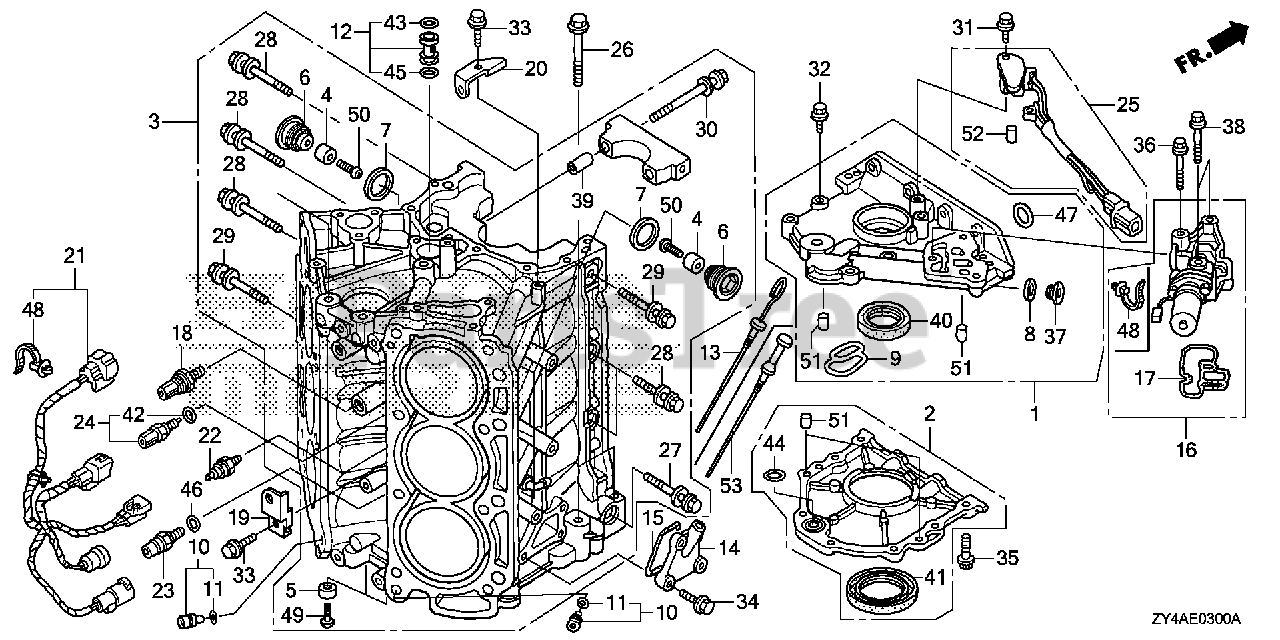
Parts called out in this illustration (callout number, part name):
1	COVER ASSY., CRANKCASE (UPPER) *NH8* (DARK GRAY)
2	CASE ASSY., OIL SEAL
3	BLOCK ASSY., CYLINDER *NH8* (DARK GRAY)
4	METAL, ANODE
5	METAL, ANODE
6	BOLT, SEALING (22MM)
7	WASHER, SEALING (22MM)
8	WASHER, SEALING (22MM)
9	GASKET, OIL HOLE
10	ORIFICE ASSY., OIL CONTROL
11	O-RING (8.8X2.4)
12	JOINT ASSY., OIL PIPE
13	DIPSTICK, OIL
14	COVER, OIL LEVEL GAUGE
15	GASKET, OIL LEVEL GAUGE
16	VALVE ASSY., SPOOL *NH8* (DARK GRAY)
17	FILTER ASSY., SPOOL VALVE
18	SENSOR, KNOCK
19	BRACKET, CLIP B
20	BRACKET B, HARNESS CLIP
21	WIRE, SWITCH
22	SWITCH ASSY., OIL PRESSURE
23	SWITCH ASSY., OIL PRESSURE
24	SENSOR ASSY., WATER TEMPERATURE
25	SENSOR ASSY., CRANK
26	BOLT, FLANGE (12X95)
27	BOLT-WASHER (10X109)
28	BOLT-WASHER (10X60)
29	BOLT-WASHER (10X80)
30	BOLT-WASHER (11X105)
31	BOLT, FLANGE (6X16)
32	BOLT, FLANGE (6X35)
33	BOLT, FLANGE (6X14)
34	BOLT, FLANGE (6X18)
35	BOLT, FLANGE (6X22)
36	BOLT, FLANGE (8X75)
37	BOLT, SEALING (22MM)
38	BOLT, FLANGE (8X50)
39	PIN, DOWEL (13X37)
40	OIL SEAL (41X66X8)
41	OIL SEAL (80X98X10) (ARAI)
42	O-RING (9.5X1.9)
43	O-RING (18.3X3.5)
44	O-RING (26.2X2.4) (YAMADA SOMBOON)
45	O-RING (16.3X3.5)
46	O-RING (13X1.5) (ARAI)
47	O-RING (25X2.4) (NOK)
48	CLIP, HARNESS BAND (145MM) (BLACK)
49	SCREW, PAN (5X16)
50	SCREW, PAN (5X20)
51	PIN, DOWEL (6X10)
52	PIN, DOWEL (5X8)
53	DIPSTICK, OIL
